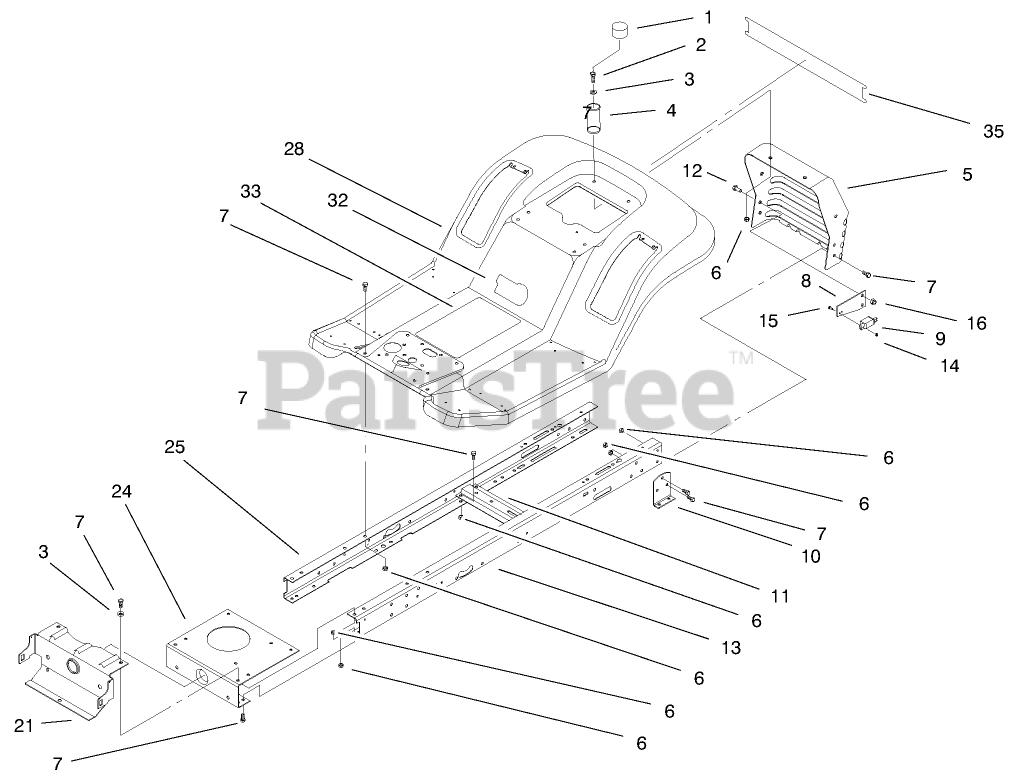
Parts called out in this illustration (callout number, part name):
1	CAP-PROTECTOR
2	SCREW-HH
3	WASHER-PLAIN
4	SPRING-COMPRESSION
5	SUPPORT-SEAT/REAR HITCH
6	NUT-LOCK, NI
7	SCREW-HH
8	PLATE-SWITCH
9	SWITCH-POLE, SINGLE
10	BRACKET-TRANSAXLE, MOUNTING
11	BRACKET-IDLER PIVOT
12	SCREW-HH
13	RAIL-FRAME, LH
14	NUT-LOCK
15	SCREW-SHH
16	NUT-LOCK, NI
24	PLATE-MOUNTING, ENGINE
25	RAIL-FRAME, RH
28	REAR BODY ASM
32	DECAL - USA
33	DECAL-GEAR
33	DECAL-INSTRUCTION
35	DECAL-REAR, BODY
